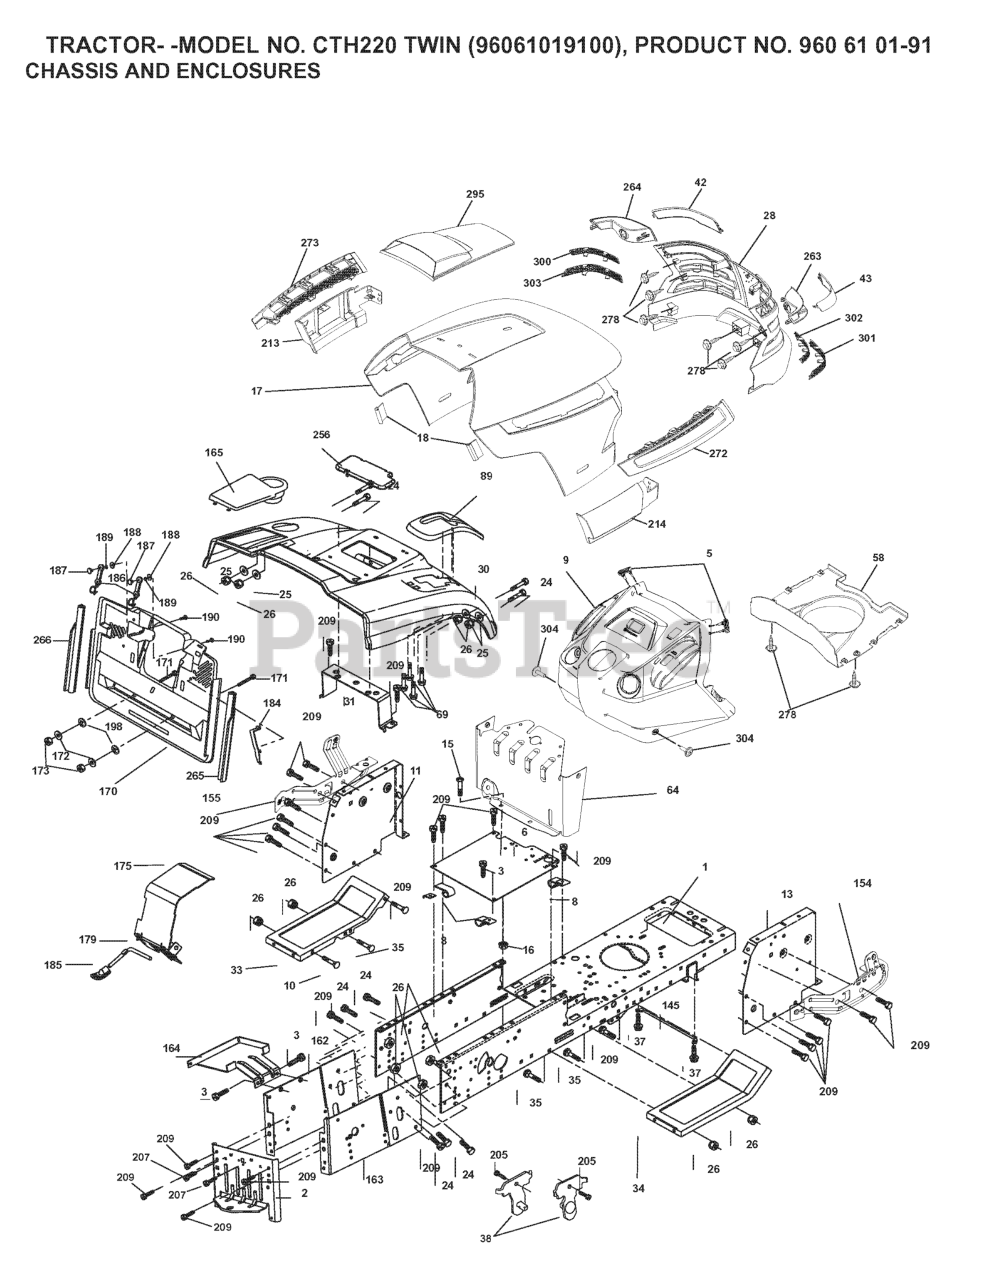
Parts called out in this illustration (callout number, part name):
2	DRAWBAR
3	SCREW 3/8-16X3/4
5	BUMPER DASH
6	PLATE
8	CLIP,INSULATOR
10	BOLT D
11	PANEL DASH LH
13	PANEL DASH RH
15	Screw, Machine, Truss Head 5/16-18 UNC x 3/4
16	NUT
17	HOOD
18	BUMPER.HOOD.TEX.HUSQVARNA
25	WASHER
26	NUT
28	GRILL.ASM.HUSQ.TG/CRD.W/TRIM
30	CONSOLE.CRD.AUTO.GRY
31	BRACKET SUPPORT FENDER
33	FOOTREST PNT LH
34	FOOTREST PNT RH
37	Screw 5/16-18 x 1/2 Hex, Self Tapping 5/16-18 x 1/2
38	BRACKET ASM PIVOT MOWER REAR
42	LENS.LH.TEX.GT.HUSQ.CL
43	LENS.RH.TEX.GT.HUSQ.CL
58	AIR.DUCT.HOOD.TEX.GT.HUSQ
64	DASH LOWER
69	SCREW.HI-LO.CONSOLE
89	CONSOLE.CRD.AUTO.GREY.2005
145	ROD PIVOT CHASSIS/HOOD
162	BRACKET
163	BRACKET EXTEN CHASSIS RH CRD
165	RP.COVER.BATTERY.CRD.GREY
172	WASHER
175	DOOR TRAP
179	ROD PIVOT FBI
184	BRACKET.ACTUATOR.BAGGER.SRD
186	LATCH ASSY
187	WELDNUT
189	LOCKWASHER #10
190	SCREW
207	SCREW, 5/16-18 X 1/2
209	SCREW, 3/8-16X3/4
213	SKIRT.HOOD.SIDE.HUSQ.LH.GREY
214	SKIRT.HOOD.SIDE.HUSQ.RH.GREY
256	COVER FENDER CRD
263	BEZEL.RH.TEX.GT.HUSQ
264	BEZEL.LH.TEX.GT.HUSQ
265	SEALING
266	SEALING
272	VENT.SIDE.HOOD.HUSQ.RH.GREY
273	VENT.SIDE.HOOD.HUSQ.LH.GRAY
278	SCREW
295	VENT.ASM.HOOD.TOP.TEX.
300	INSERT.HEX.GRILL.HUSQ.
301	INSERT.HEX.GRILL.HUSQ.GREY
302	INSERT.HEX.GRILL.HUSQ.
303	INSERT.HEX.GRILL.HUSQ.
304	SCREW 14-20 X 5/8
